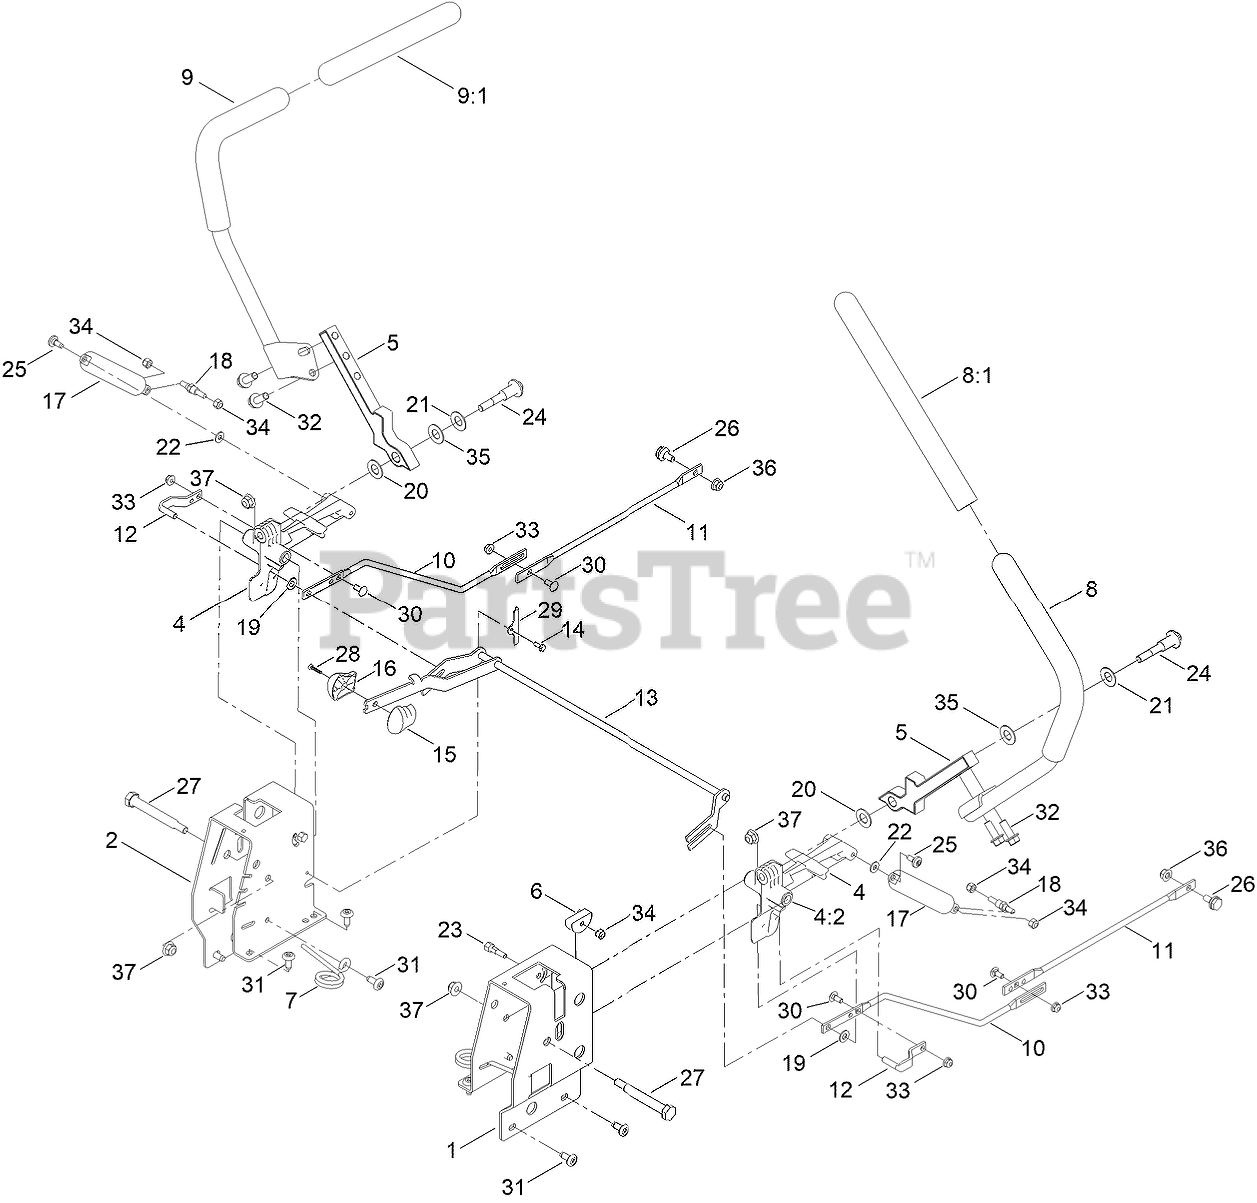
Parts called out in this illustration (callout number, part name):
1	PLATE-CONTROL BOX, LH
2	PLATE-CONTROL BOX, RH
4	ACTUATOR ARM ASM
4:2	BUSHING-FLANGE
5	ARM-CONTROL
6	ECCENTRIC
7	SPRING-TORSION
8	HANDLE-CONTROL, LH
9	HANDLE-CONTROL, RH
10	ROD-HYDRO, FRONT
11	ROD-HYDRO, REAR
12	PIN-ROD, HYDRO
13	SPEED CONTROL ASM
14	PLATE-RETAINER
15	KNOB-RH
16	KNOB-LH
17	DAMPER-NON CAVITATING
18	STUD-DAMPER
19	SPACER-NYLON
20	WASHER-NYLON
21	WASHER-BELLEVILLE
22	WASHER
23	BOLT-PIVOT, ECCENTRIC
24	BOLT-PIVOT
25	SCREW-SHOULDER
26	BOLT-SHOULDER,HFH
27	BOLT-PIVOT
28	SCREW-PPH
29	SCREW-TAPTITE
30	BOLT-CARR
32	SCREW-HHF
33	NUT-HF
34	NUT-HEX
35	WASHER
36	NUT-HF
37	NUT-HF, NI
